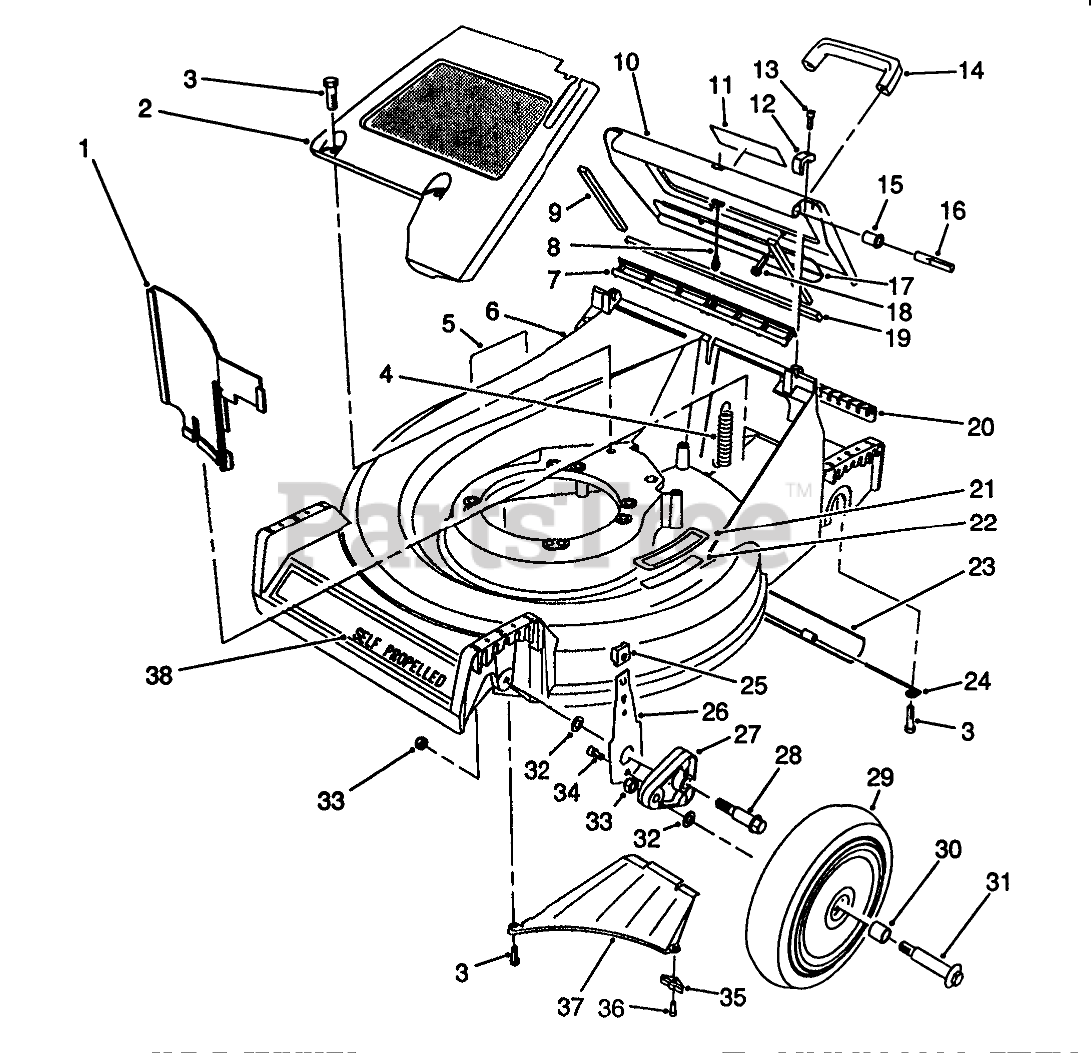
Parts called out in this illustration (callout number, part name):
1	PANEL-VERTICAL
2	PaneI-Screen
3	SCREW-HWHTF
4	EXTENSION-SPRING
5	DECAL-DANGER
6	21" Housing Assembly (Incl. Ref. #5, 21-22)
7	DOOR SEAL
8	DOOR CABLE
9	DOOR SIDE SEAL
10	Door-Discharge (Incl. Ref. #9, 11, 17 & 19)
11	DECAL - WARNING
12	HINGE CLAMP
13	SCREW-HSH
14	HANDLE-DOOR
15	DOOR BUSHING
16	HINGE PIN
17	DOOR - BRACE
18	SCREW-HWH
19	DOOR END SEAL
20	ACCESS COVER
21	STEP PAD
22	STEP PAD DECAL
23	TRAILING SHIELD
24	LH SHIELD HANGER
25	KNOB-ARM
26	FRONT SPRING ARM ASM
27	ARM-PIVOT, FRONT
28	BOLT-SHOULDER
29	Wheel & Tire Assembly (Incl. Ref. #30)
30	BUSHING
31	WHEEL BOLT
32	WASHER
33	Nut
34	SCREW-HSH, THREAD FORMING
35	Bracket-Discharge
36	SCREW-HWHTF
37	Ramp Discharge
38	DECAL - DECK
